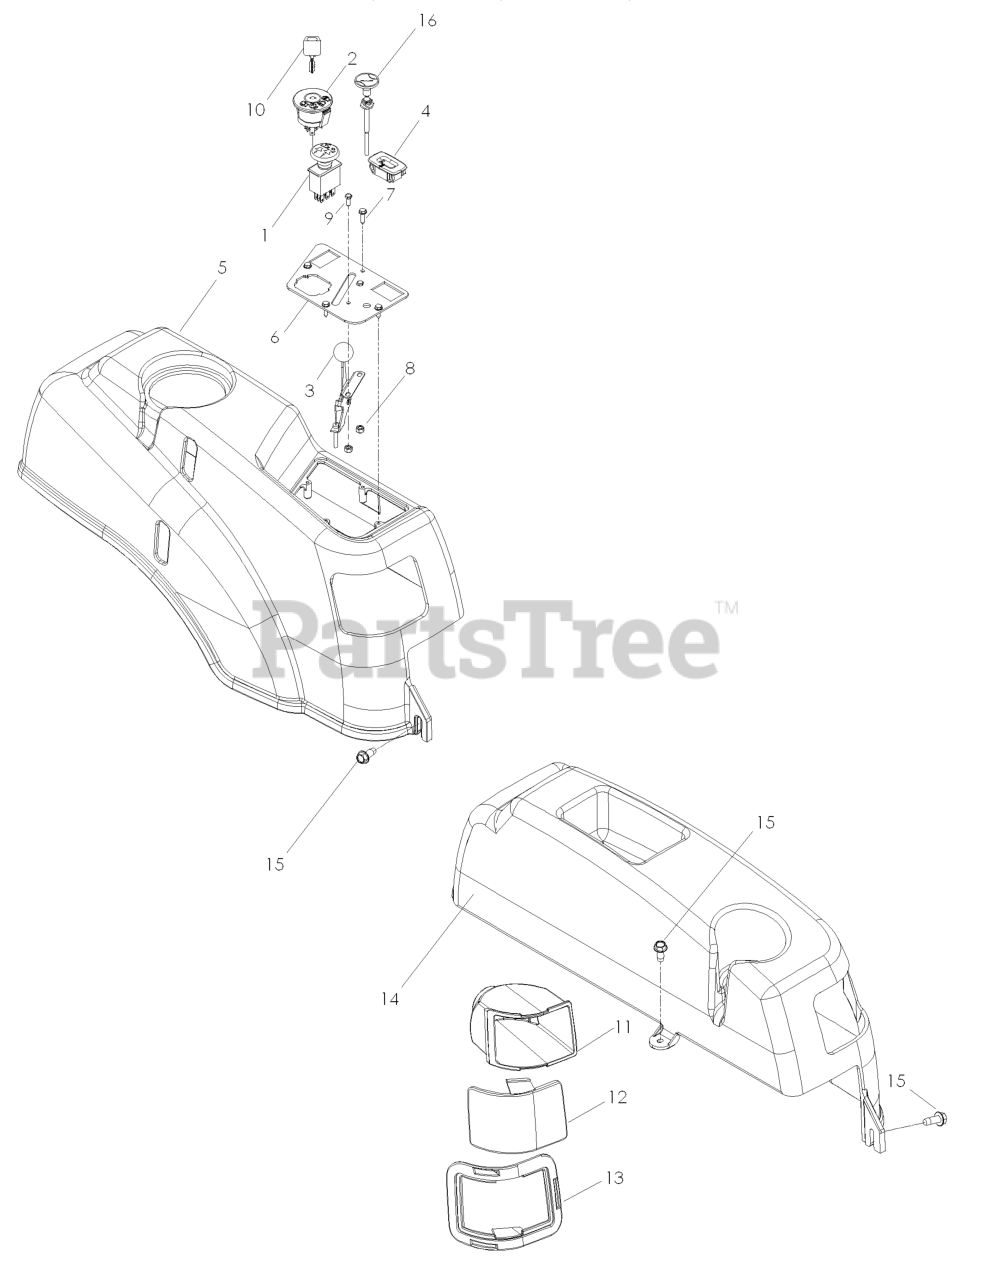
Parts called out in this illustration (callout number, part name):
1	RP.SWITCH, BLADE
2	RP IGNITION SWITCH
3	THROTTLE CABLE
4	HOUR METER
5	RP.FENDER, RT
6	CONSOLE.PLATE.BLACK
7	SCR #10-12X3/4 HEX WAS HD ZD
8	NUT 10-24 NYLOC
9	HCS #10-24 X 1/2
10	KEY
11	LEFT HEADLIGHT REFLECTOR
11	RT HEADLIGHT REFLECTOR
12	LENS, COLORED LEFT
12	LENS, COLORED RIGHT
13	RT HEADLIGHT RIM GREY
13	LEFT HEADLIGHT RIM GREY
14	FENDER, LT
15	SCREW 1/4 X 5/8
16	CHOKE CONTROL
